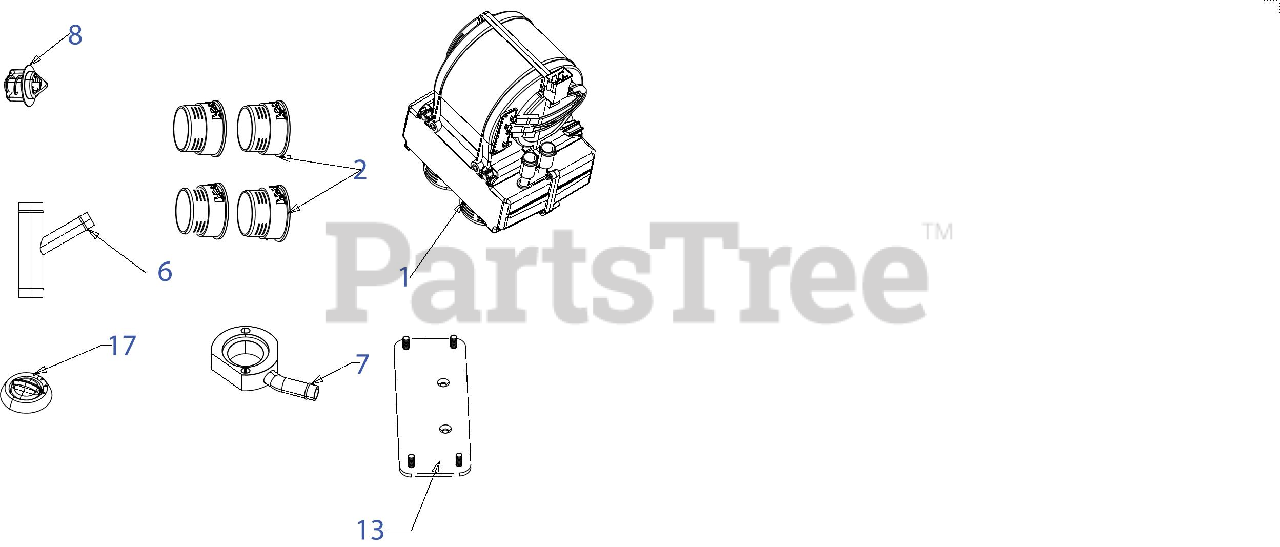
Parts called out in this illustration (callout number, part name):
1	UNDERHOOD HEATER
6	1" ALUMINUM Y-FITTING
7	THERMOSTAT BYPASS KIT BP106
8	72 DEGREE C THERMOSTAT WITH SEAL
13	COMPACT UNDERHOOD MOUNTING BRACKET
17	3 SPEED FAN SWITCH
